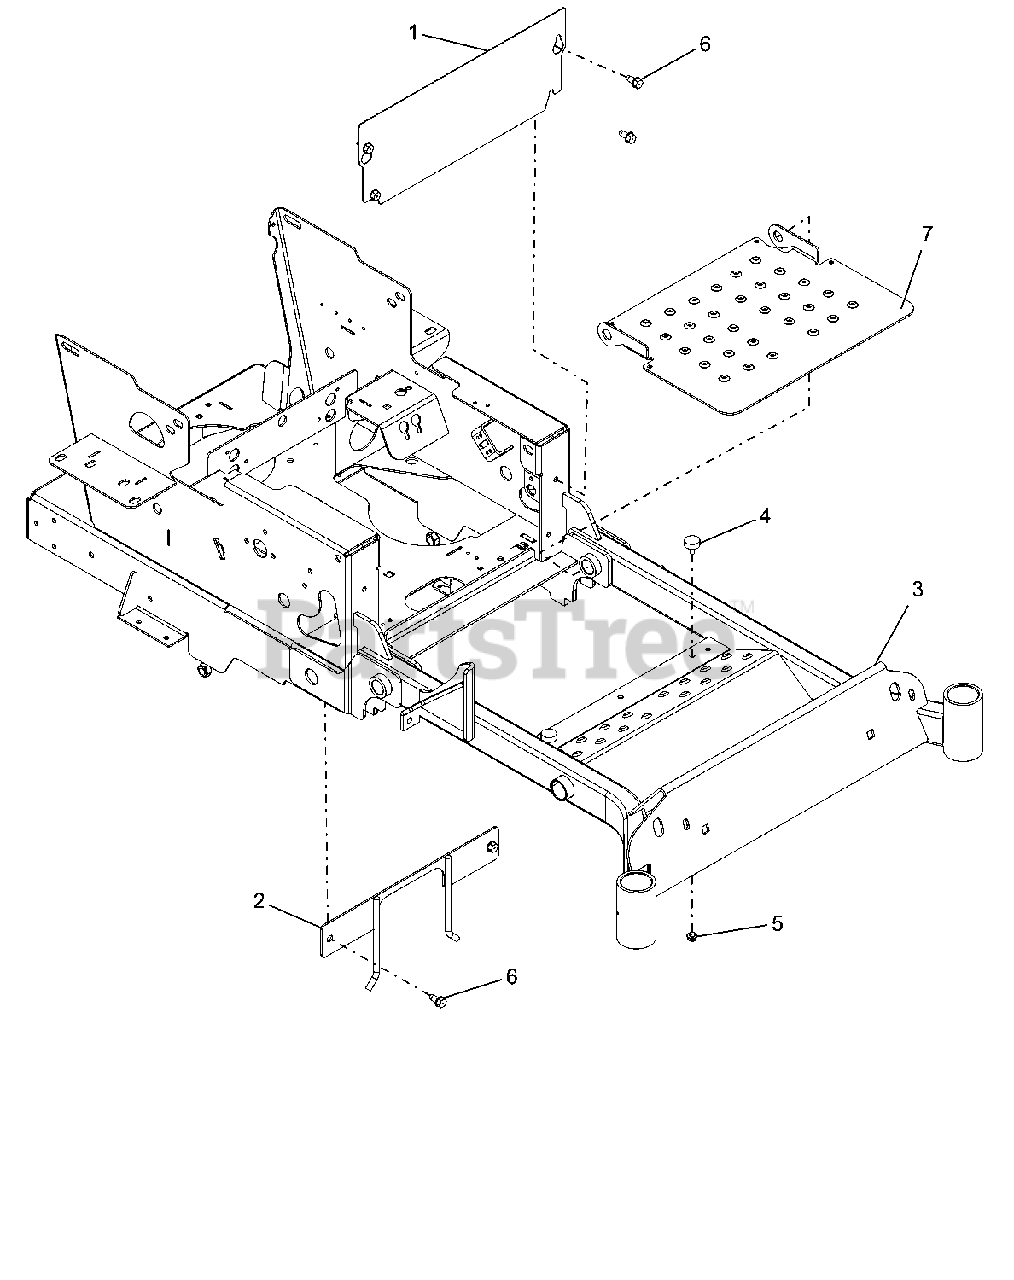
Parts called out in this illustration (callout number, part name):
1	PLATE, KICK
2	PTO BELT FINGER WLDMT - BLK
3	HD 44-48 FRAME W/SAFETY DECALS
4	BUMPER, RUBBER
5	@NUT-SPNLK-FLG .312-18 YWZC
6	@SCR-TAP .38-16X.75 HWH TR YWZ
7	PANEL, INSPECTION
